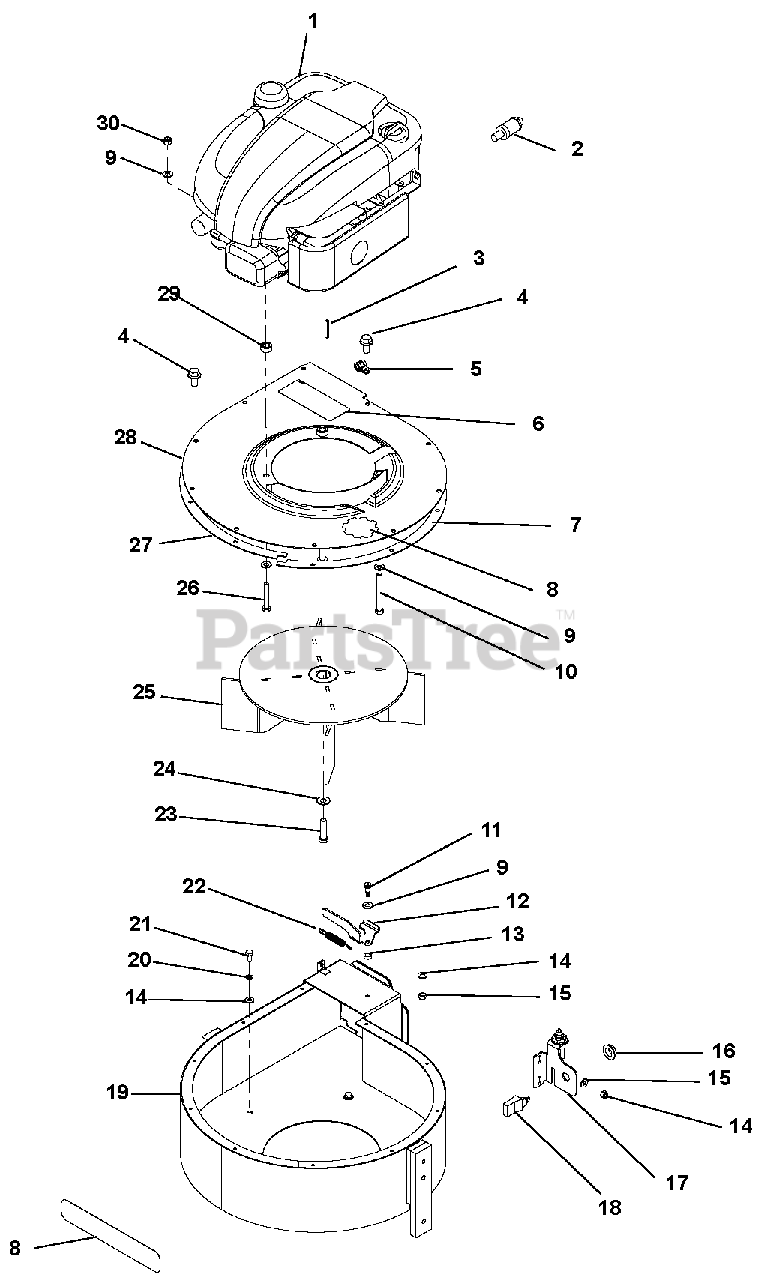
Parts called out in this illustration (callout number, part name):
1	Valve, Oil Drain (6783A)
2	Briggs and Stratton Pro 850
3	3/16 X 1.3/8" Long Key
4	Screw, Hex, Flange .25-20 X .63 SLFTAP
5	Cushioned Loop Clamp, 3/8"
6	Decal, Danger Read Manual
7	APV Fan Housing Gasket, Left .062
8	Decal, Parker Logo
9	Washer, Flat, Steel .344 X .688 X .065
10	Bolt, Hex .31-18 X 3.00
11	Bolt, Shoulder .313 X .250 X .250-20
12	APV Hold Down Lever
13	Spacer .316 X .498 X .197
14	Washer, Flat, Steel .281 X .62 X .065
15	Nut, Locking, Nylon .250-20
16	Switch Nut 9250
17	APV Bracket Switch .125R 1S2B
18	SE Switch, Delta
19	APV Fan Housing Weldment Assembly
20	Washer, Locking .25 X .062 Regular
21	Bolt, Hex .25-20 X .63
22	Spring, Return .313 X .438 X 2.93
23	Bolt, Hex .38-24 X 1.50
24	Washer, Belleville .38 (90127A031)
25	APV Fan Assembly, Balanced
26	Bolt, Hex .31-18 X 2.00
27	APV Fan Housing Gasket, Right .062
28	Deck Weldment with Decals
29	Spacer .413 X .75 X .39
30	Nut, Locking, Nylon .312-18
31	Decal, Parker, Heritage, Small
